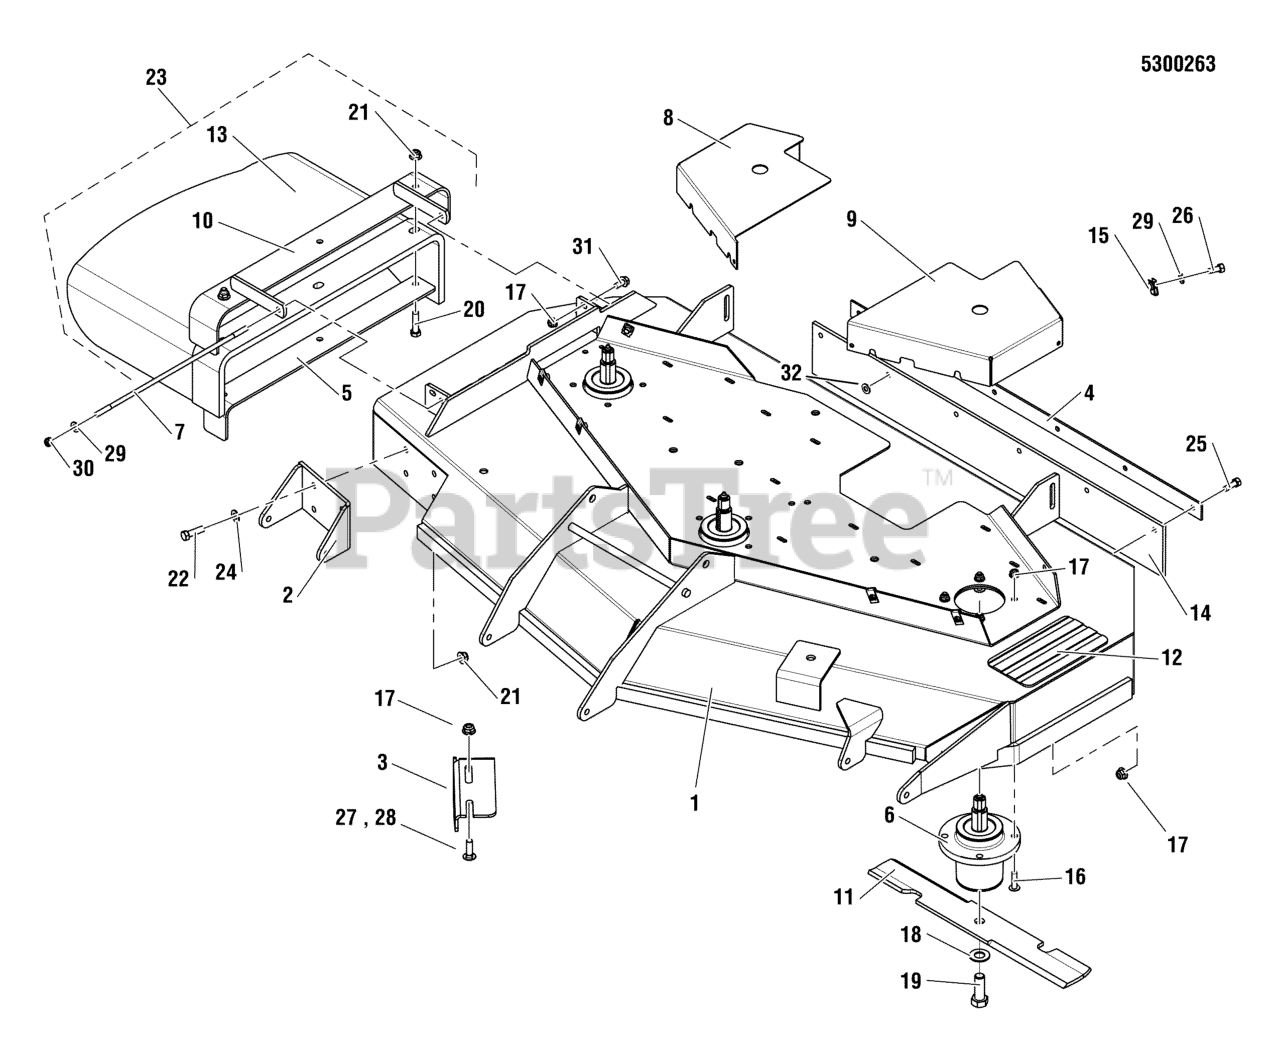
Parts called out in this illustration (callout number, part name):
1	DECK SHELL W/DECALS, IS1500Z 2552
2	PLATE, BRACKET, ANTI SCALP - RED
3	PLATE, DEFLECTOR, 52" - BLK
4	PLATE, SUPPORT - BLK
5	SUPPORT, DISCHARGE CHUTE - BLK
6	ASSM, SPINDLE, LOW PROFILE
7	ROD MOUNT, CHUTE
8	GUARD, 52" DECK - RH - RED
9	GUARD, 52" DECK - LH - RED
10	WELD, FRAME, CHUTE, 61 - RED
11	BLADE, 18 X .25 X 2.5, 1 X 3.5 (SET OF THREE)
12	SAFETY WALK, 4.00 X 7.50
13	CHUTE, DISCHARGE, RUBBER, 61/72, BENT
14	FLAP, STRIPER, 61" DECK, IS3100, S200X
15	BODY CLIP, 5/16-18-7GA MATERIAL
16	BOLT, 5/16-18 X 1 1/4 FLANGE
17	NUT, 5/16-18 HEX NYLOCK FLANGE
18	WASHER, 5/8 GRADE 8, YZ
19	BOLT, 5/8-11 X 1-3/4 GD8
20	BOLT, 3/8-16 X 1-1/2" GD5 CZ
21	NUT, 3/8-16 HEX NYLOCK FLANGE
22	BOLT, 3/8-16 X 1-1/4" GD5 CZ
23	PURCHASE INDIVIDUAL REPLACEMENT PARTS
24	WASHER, 3/8 SAE
25	BOLT, 5/16-18 X 1 GD5 YZ
26	BOLT, 5/16-18 X 3/4 GD5
27	BOLT, 5/16-18 X 3/4, CARRIAGE
28	BOLT, 5/16-18 X 1, CARRIAGE
29	WASHER, 5/16" SAE
30	NUT, 5/16-24 HEX NYLON LOCK
31	BOLT, 5/16-18 X 3/4 GD5
32	5/16 PUSH-ON NUT RETAINER, STL, CZ
